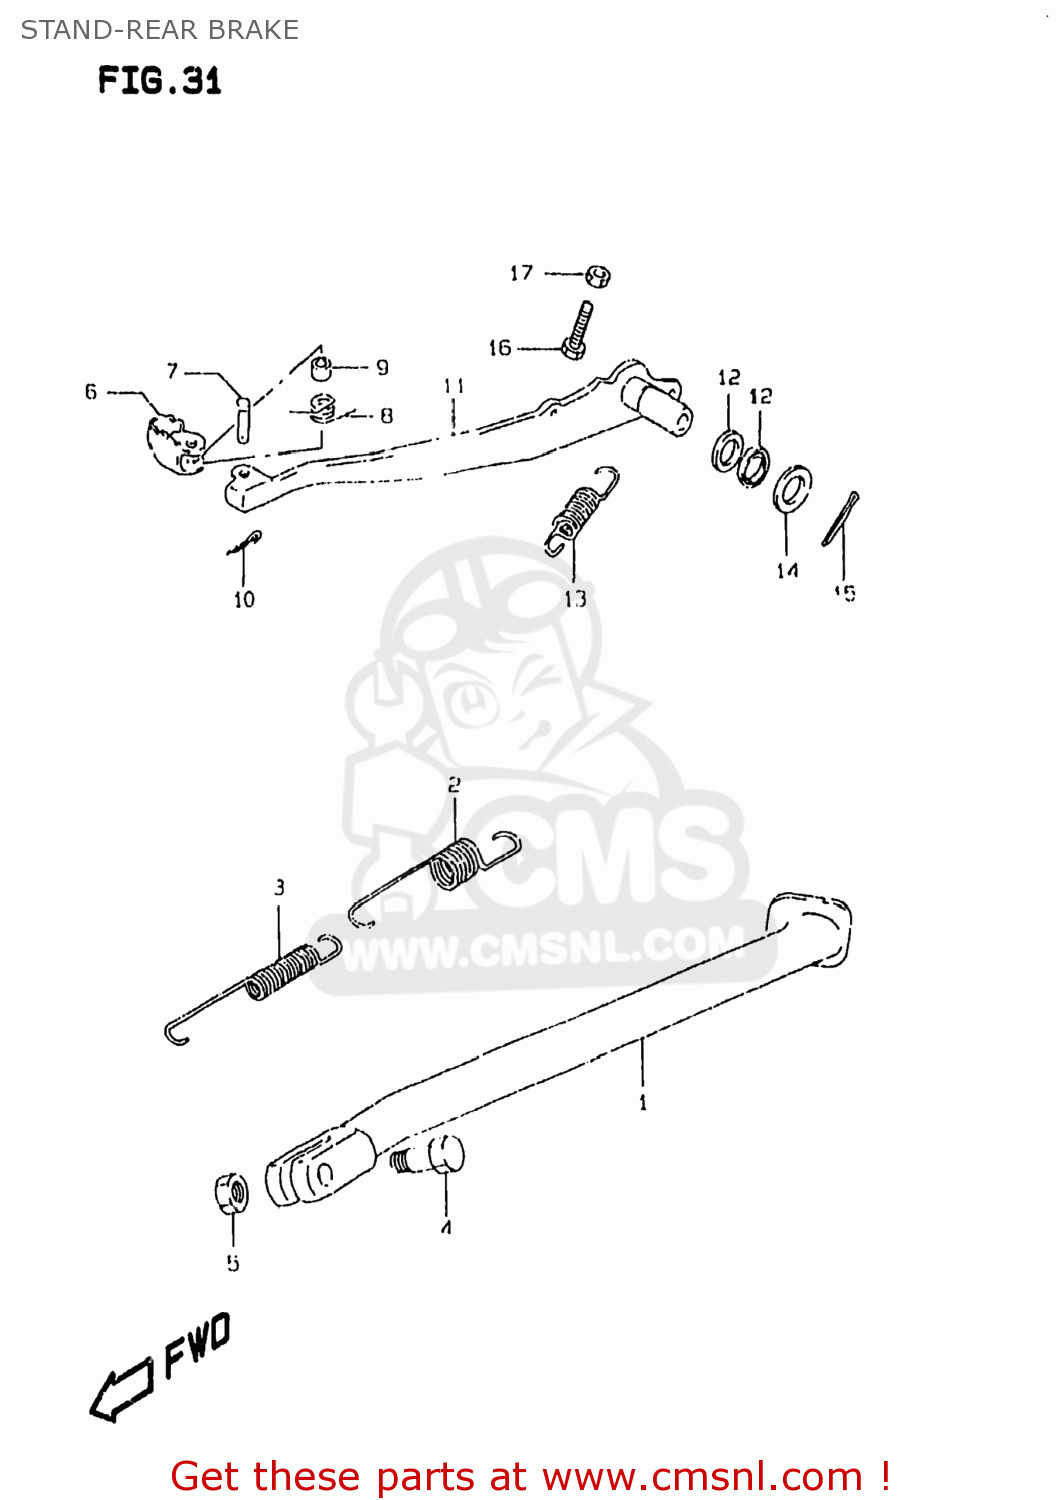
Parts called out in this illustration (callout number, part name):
1	STAND,PROP(BLACK)
2	SPRING
3	SPRING
4	BOLT(10X30)
5	NUT
6	PEDAL,BRAKE
7	PIN
8	SPRING
9	SPACER(6.5X9X6.5)
10	PIN
11	ARM,BRAKE PEDAL
12	SEAL,OIL(15X21X3)
13	SPRING
14	WASHER(15.5X26X2.3)
15	COTTER PIN
16	BOLT(6X23)
17	NUT 6MM
